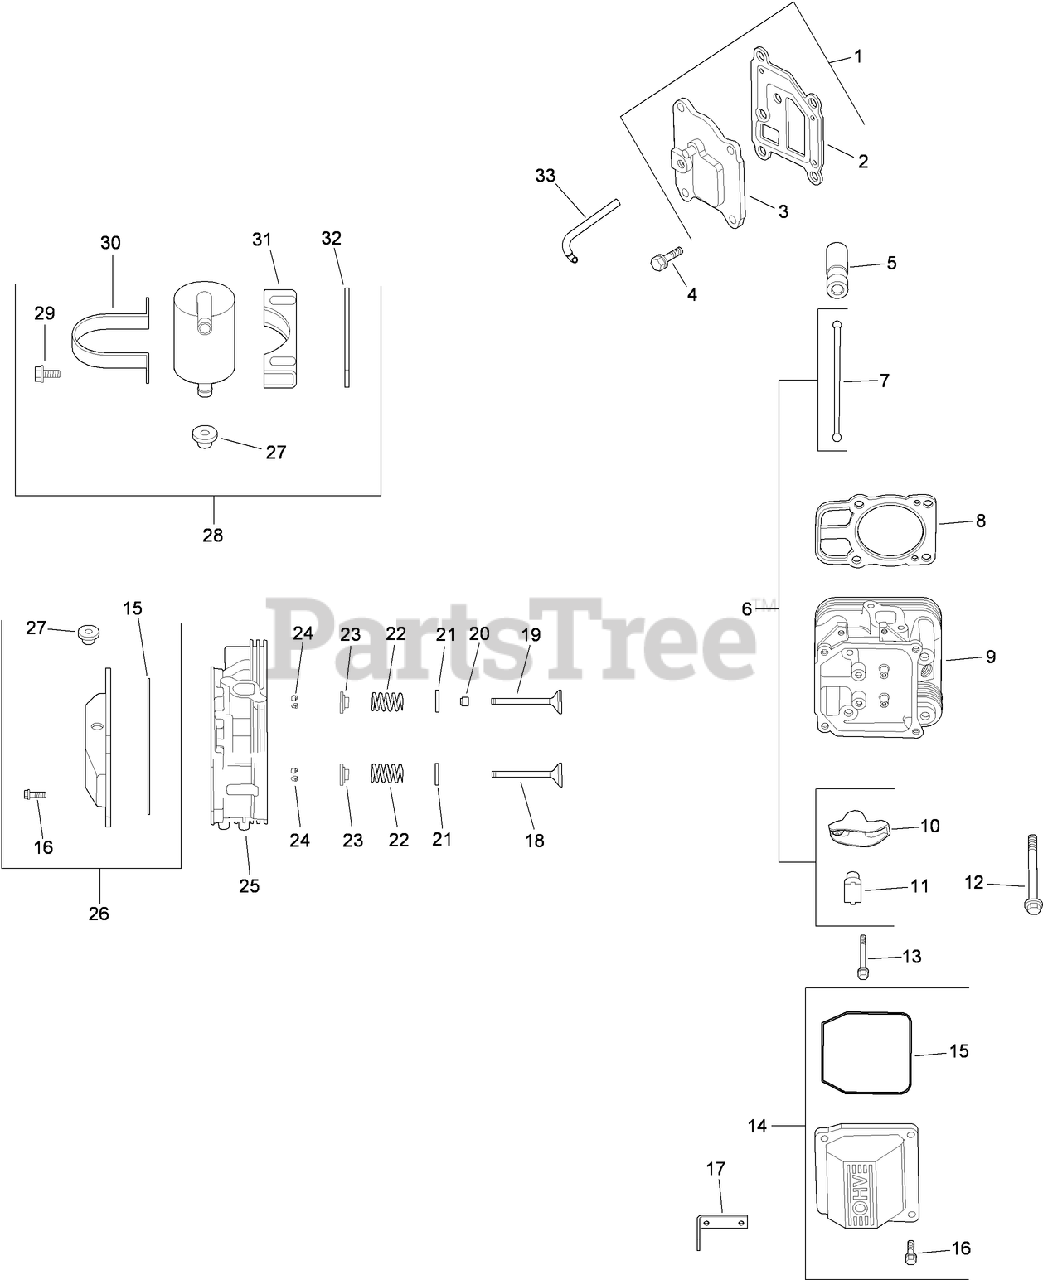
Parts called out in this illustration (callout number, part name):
1	breather cover w/gasket Kit (INCLUDES 2, 3)
2	GASKET-BREATHER
3	Cover-Breather
4	SCREW-HHFTF (M6X1.0X20)
5	HYDRAULIC VALVE LIFTER KIT (INCLUDES 25 357 14-S)
6	VALVE TRAIN KIT (INCLUDES 7, 10, 11)
7	ROD-PUSH
8	Cylinder Head Gasket Kit
9	CYLINDER HEAD ASM (CYLINDER No.2)
10	PIVOT-ARM, ROCKER
11	ARM-ROCKER
12	SCREW-FLANGE (M6X1.0X34)
13	SCREW
14	PLAIN ROCKER COVER KIT (INCLUDES 15 QTY 1], 16 QTY 4])
15	O-RING (VALVE COVER)
16	SCREW-FLANGE (M6X1.0X30)
17	STRAP-LIFTING
18	VALVE-EXHAUST (STD)
18	VALVE-EXHAUST (.25)
19	VALVE-INTAKE (STD)
19	VALVE-INTAKE (.25)
20	SEAL-STEM, VALVE
21	RETAINER-SPRING
22	SPRING-VALVE
23	CAP-SPRING, VALVE
24	RETAINER KIT
25	CYLINDER HEAD ASM (CYLINDER No.1)
26	BREATHER VALVE COVER ASM (INCLUDES 15 QTY 1], 16 QTY 4], 27)
27	GROMMET-RUBBER
28	BREATHER VALVE COVER KIT (INCLUDES 27, 29-32)
29	SCREW-FLANGE, THREAD FORMING (M5X0.8X16)
30	STRAP-BREATHER
31	BRACKET-SEPARATOR, BREATHER
32	Spacer
33	HOSE-BREATHER
